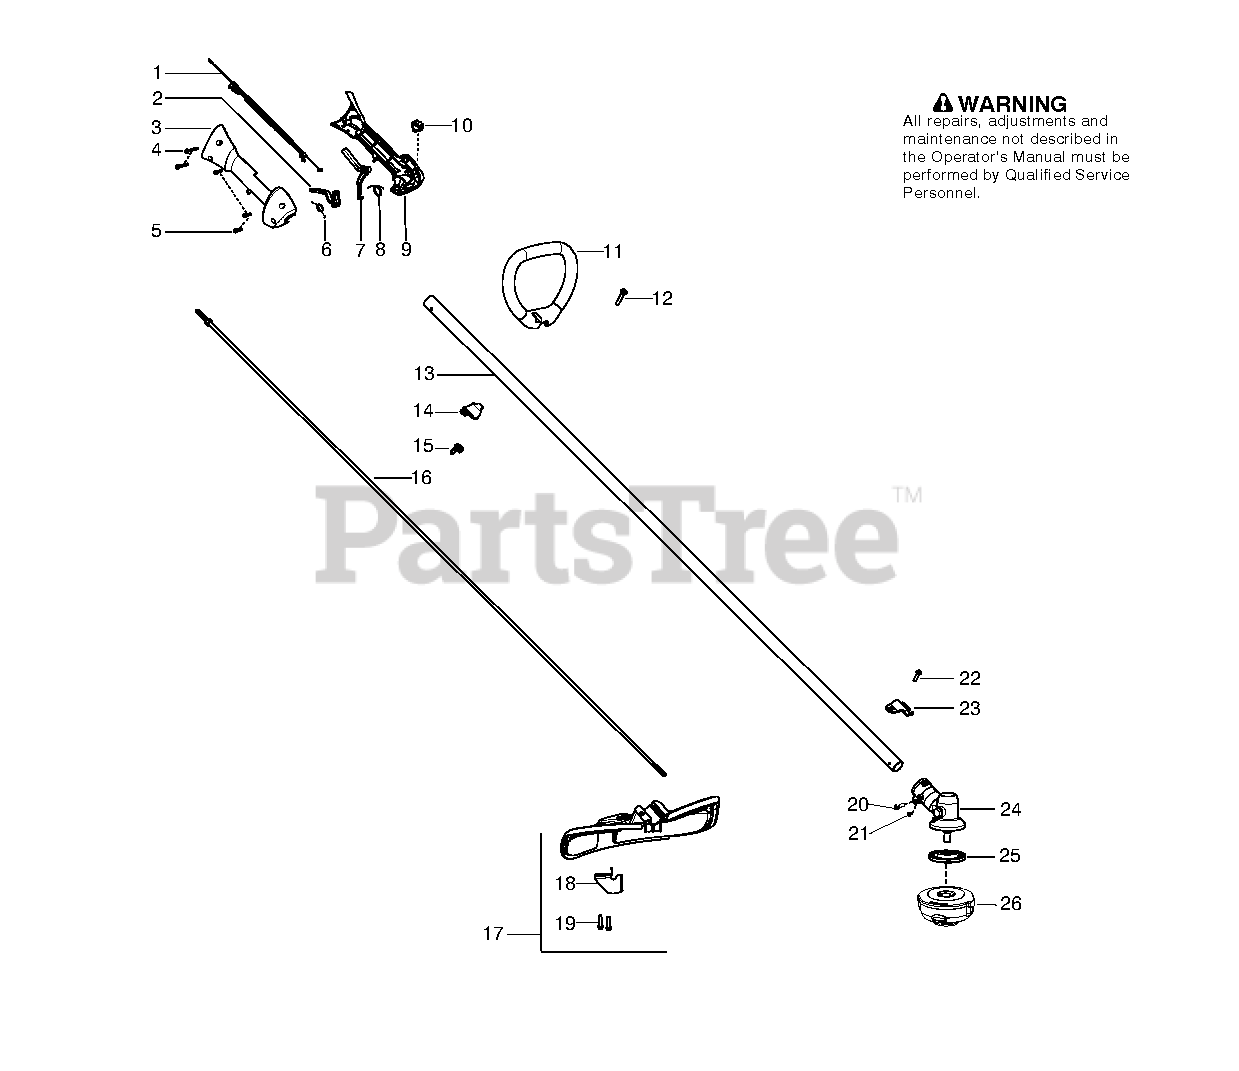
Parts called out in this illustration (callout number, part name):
5	SCREW M4 X 1.75 PT 16MM
6	SPRING TRIGGER
8	SPRING LOCKOUT
10	KIT SWITCH
11	HANDLE ASSIST
12	BOLT, TYPE 2
13	KIT DRIVESHAFT SST
14	CLAMP ASSIST HANDLE
15	WINGNUT, TYPE 2
16	FLEXSHAFT 57"
17	KIT SHIELD
18	LINE CUTTER
20	SCREW - CARB. ADAPTOR
22	SCREW 1/4-20 X 7/8 (TAP
23	BRACKET SHIELD STRAIGHT SHAFT
24	ASSY GEARBOX
25	DRIVE DISC
26	T25 10MM LH TRIMMER HEAD
